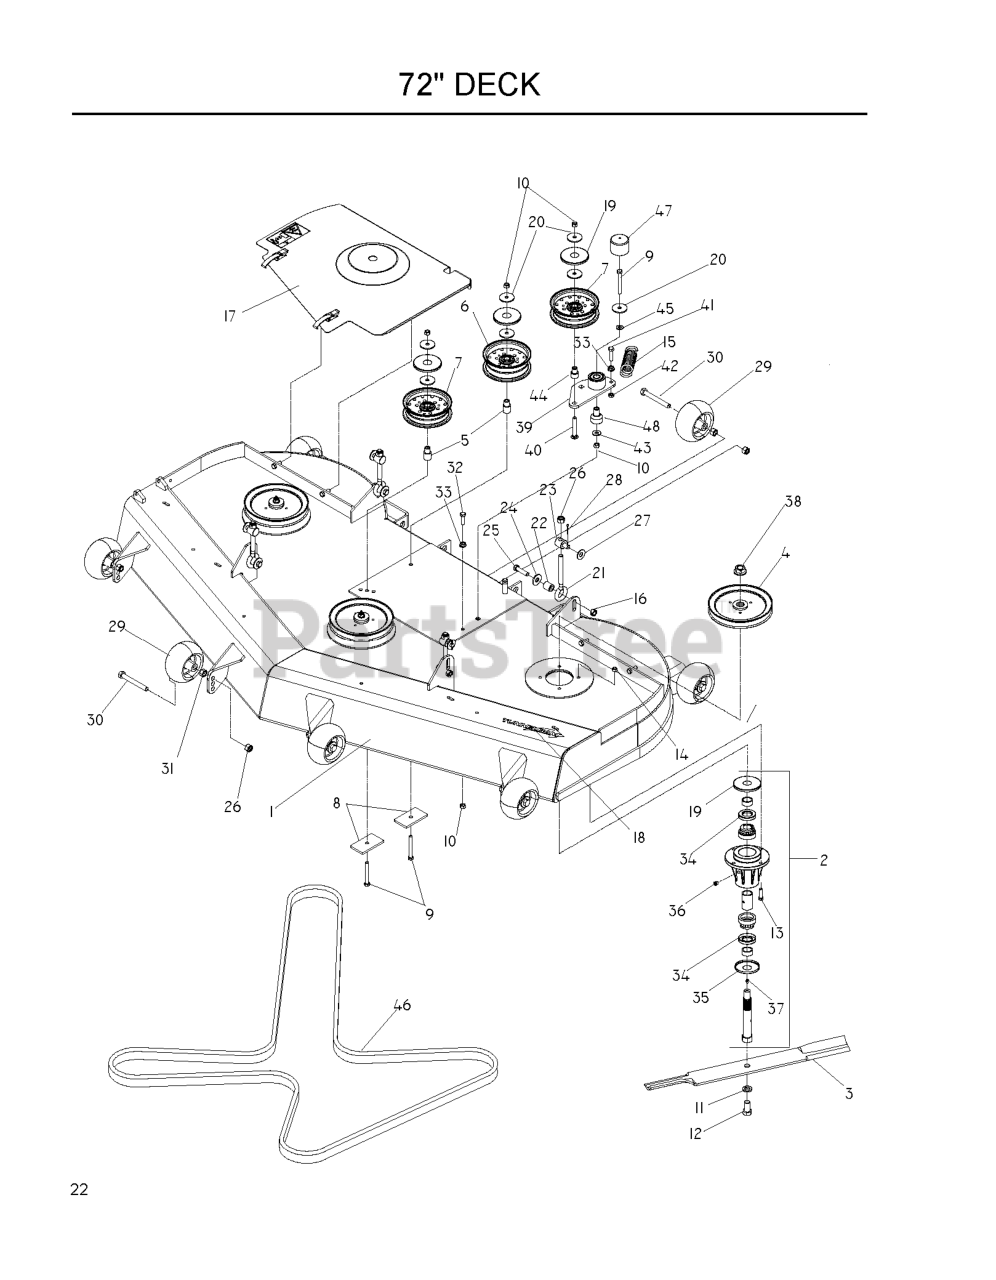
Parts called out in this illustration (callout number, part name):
1	DECK W/DECALS 72" HUS
2	HSG KIT 72 RIBBED
3	BLADE OEM - 25"
4	PULLEY, 72
5	IDLER BUSHING
6	IDLER PULLEY (TALL)
7	IDLER PULLEY
8	SUPPORT PLATE
9	HCS 3/8C X 3
10	NUT 3/8-16 NYLOC
11	LOCKWASHER 5/8
12	HCS 5/8F X 1 1/4
13	HCS 5/16C X 1 1/4
14	NUT 5/16 NYLOC
15	DECK SPRING
16	NUT 7/16C CENTERLOCK
17	72 BELT SHIELD ASM LH
17	72 BELT SHIELD ASM - RH
18	DECAL, TUNNEL RAM 8"
19	TOP DUST CAP
20	WASHER, 3/8 SPEC
24	SPRING WASHER - .50
25	HCS 7/16 - 14 X 1 3/4
26	NUT 1/2-13 HEX NYLOC ZD
27	WASHER 1/2 FLAT
28	PIN COTTER 1/8 X 1 ZD
29	GAUGE WHEEL
30	HCS 1/2-13 X 4 GR 5 ZD
31	NUT HEX 1/2
32	HCS 3/8C X 1 1/4 GR5
33	NUT 3/8C WHIZ
34	SHAFT SEAL
35	BOTTOM DUST CAP
36	PLUG-VENTED
38	NUT FLANGE 3/4-16
39	ARM-IDLER W/BRG
40	RHSNB 3/8-16 X 2.75
41	HCS 3/8-16 X 1-1/2
42	NUT 3/8-16 HEX JAM
43	WASHER 3/8 FLAT
44	BUSHING, IDLER
45	WASHER 3/8 SAE FLAT
46	BELT, DECK 72"
47	CAP, VINYL
48	PIVOT, BEARING
